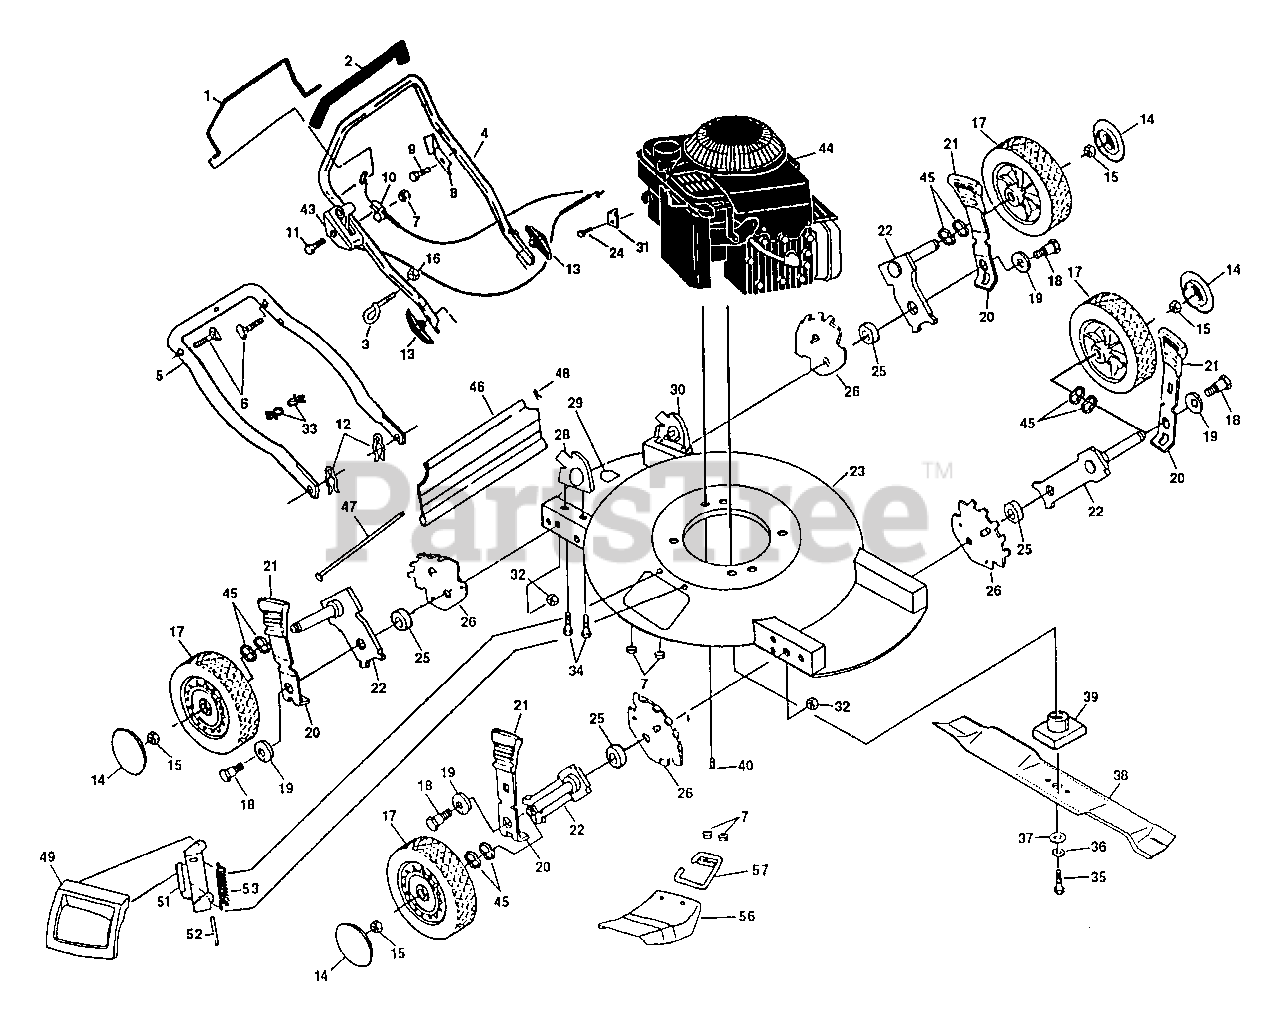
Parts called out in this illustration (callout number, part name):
1	Control Bar
2	Handle Grip
3	Rope Guide (AYP part number)
4	Upper Handle
5	Lower Handle
6	Handle Bolt 5/16-18 x 1-3/4 (AYP part number)
7	Locknut 1/4-20
8	Up-Stop Bracket
9	Hex Washer Head Screw #10-24 x 1/2
10	Engine Zone Control Cable
11	Hex Washer Head Screw 1/4-20 x 2-1/8
12	Hairpin Cotter
13	Handle Knob (AYP part number)
14	Hubcap
15	Hex Flange Locknut 3/8-16
16	Locknut 1/4-20
17	Wheel & Tire Assembly
18	Shoulder Bolt
19	Belleville Washer
20	Selector Spring
21	Selector Knob
22	Axle Arm Assembly
23	Lawn Mower Housing
24	Screw
25	Spacer
26	Wheel Adjusting Bracket (R.F./L.R.)
28	Handle Bracket Assembly (Right) (AYP part number)
29	Danger Decal (AYP part number)
30	Handle Bracket Assembly (Left) (AYP part number)
31	Clamp (AYP part number)
32	Locknut 3/8-16 (AYP part number)
33	Cable Clip
34	Thread Cutting Screw 5/16-18 x 3/4
35	Hex Head Screw 3/8-24 x 1-3/8
36	Helical Lock Washer 3/8 (AYP part number)
37	Hardened Washer
38	20" Blade
39	Blade Adapter
40	Hex Head Thread Rolling Screw 3/8-16 x 1
43	Throttle Control
45	Wave Washer
46	Rear Skirt
47	Skirt Rod
48	Retainer Clip
49	Mulcher Door Assembly (Complete)
51	Hinge Door Bracket Assembly
52	Hinge Rod
53	Torsion Spring
56	Deflector Mulcher
57	Bracket Grass Catcher Frame
